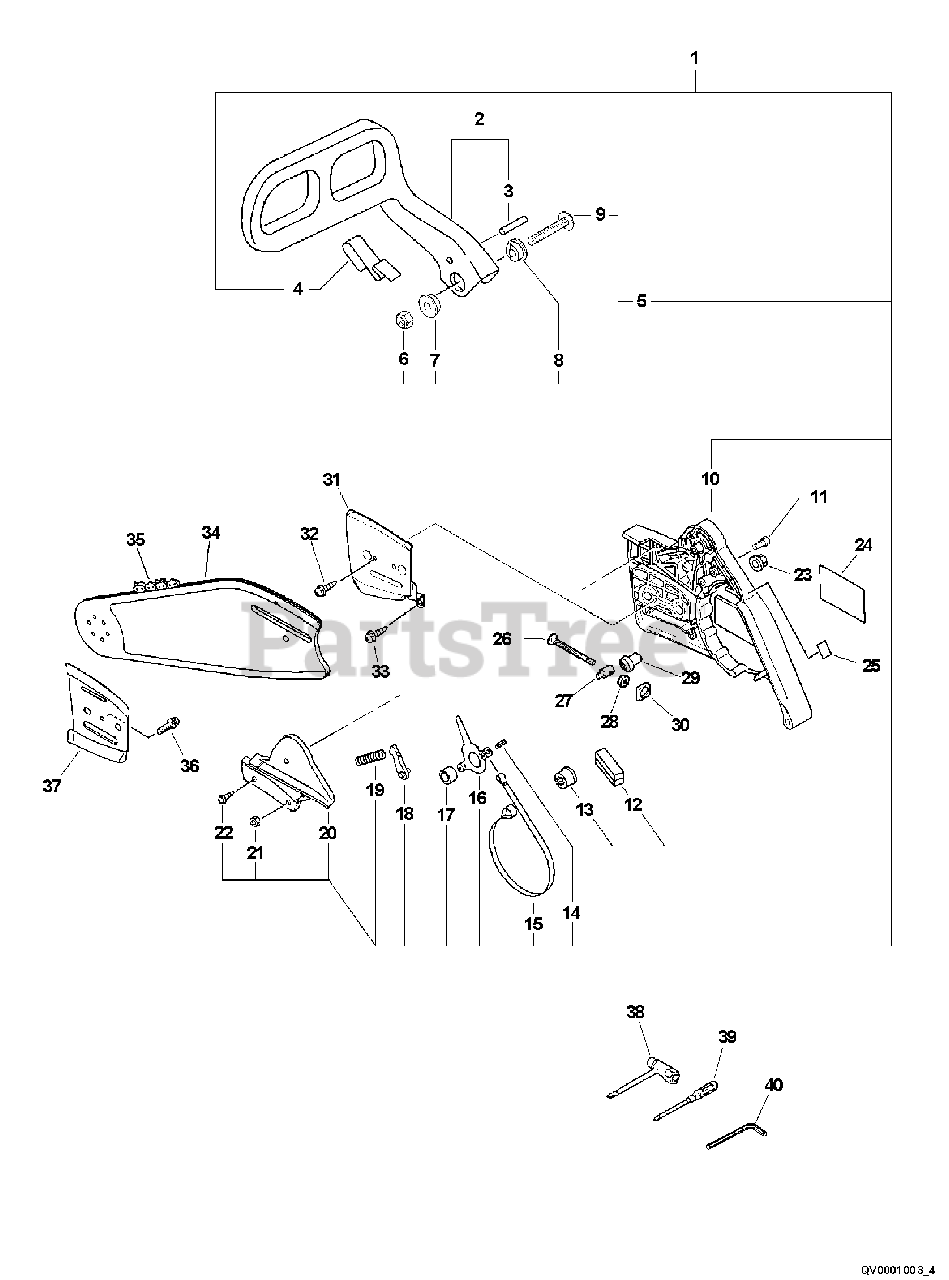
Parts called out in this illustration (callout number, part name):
1	CHAIN BRAKE ASSY
2	LEVER, BRAKE
3	PIN 3.5×26
4	SPRING, FLAT
5	SCREW KIT
6	NUT, LOCK M5
7	COLLAR 5.3×10×13×L5
8	COLLAR 5
9	SCREW 5×35
10	GUARD, SPROCKET
11	SCREW 3×18
12	SEAL, BRAKE
13	ADJUSTER, BRAKE
14	PIN, SPRING 4×8.8
15	BAND, BRAKE
16	LEVER, BRAKE
17	SPACER 8×12×9
18	STOPPER, BRAKE
19	SPRING, BRAKE
20	COVER, BRAKE
21	NUT 3 MM
22	SCREW 4×12
23	NUT, FLANGE M8×1.25
24	LABEL - ECHO
25	LABEL, OILER
27	TENSIONER, CHAIN
28	GEAR, BEVEL
29	GEAR, BEVEL
30	COLLAR - 8
31	PLATE, GUIDE - OUTER
32	SCREW 3×6
33	SCREW 4×10
34	GUIDE BAR - QUICKVENT
35	CHAIN -- CARBICHAIN QUICKVENT
36	SCREW 4×8
37	PLATE, GUIDE - INNER
38	T-WRENCH 13×19×180
39	SCREWDRIVER, PHILLIPS
40	WRENCH, ALLEN 4 MM
